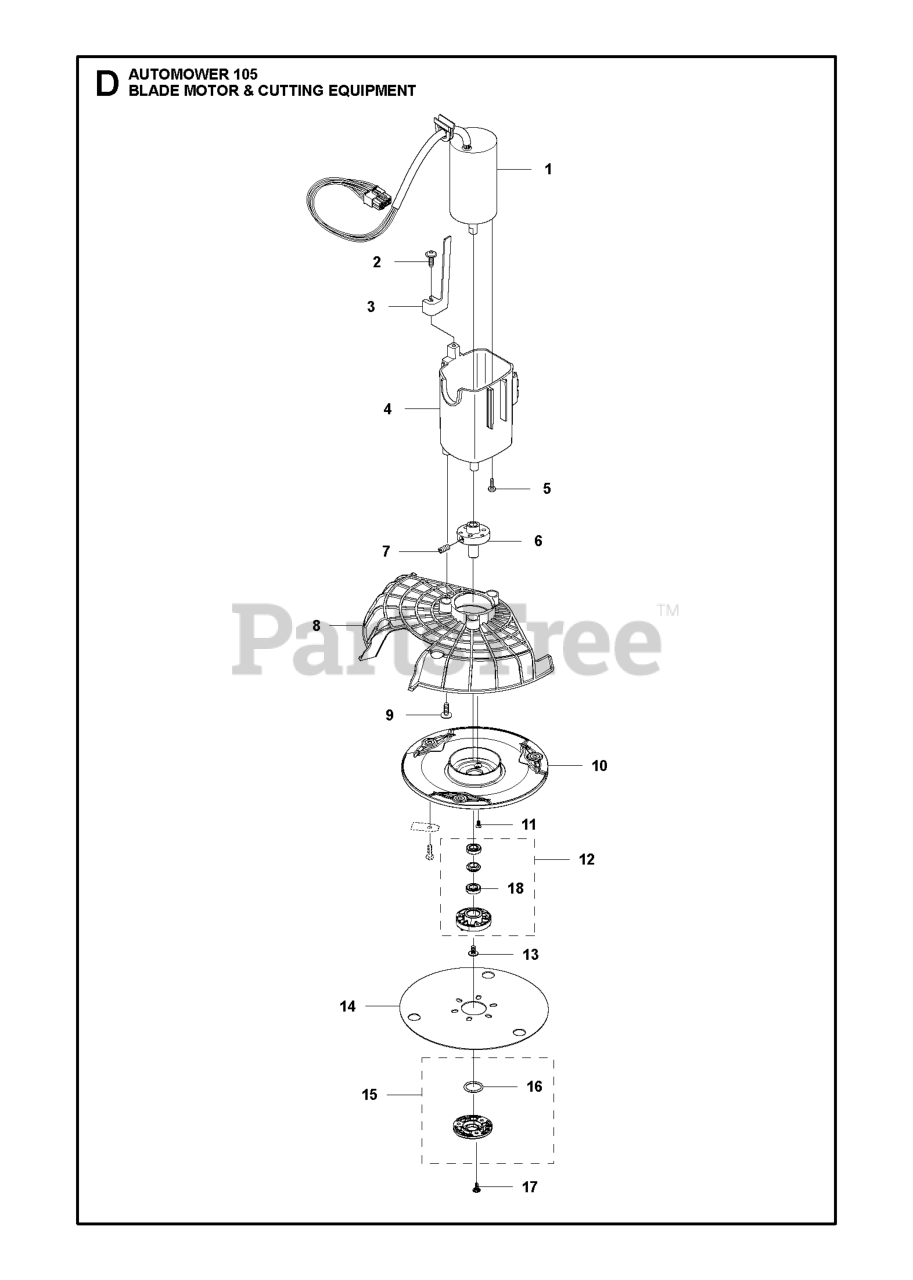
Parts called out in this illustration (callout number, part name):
1	MOTOR CUTTING, TYPE 2
2	SCREW SILVER 10MM
3	HEIGHT INDICATOR
4	MOTOR HOUSING
5	SCREW ITXPANM M4X12 A2-70 PAT
7	SCREW IHSETM M5X10 8.8 ZP-BC
8	GUARD CUTTING DISC
9	SCREW 14MM
11	SCREW TORX M4X8 8.8 NYLON PATC
12	BEARING HOUSING ASSY
13	SCREW
15	COVER KIT BEARING
16	O-RING 20X2,5 MM
17	SCREW 14MM
18	BALL BEARING BALL BEARING 535
18	BALL BEARING 2 RS,TIGHT CLEAR
